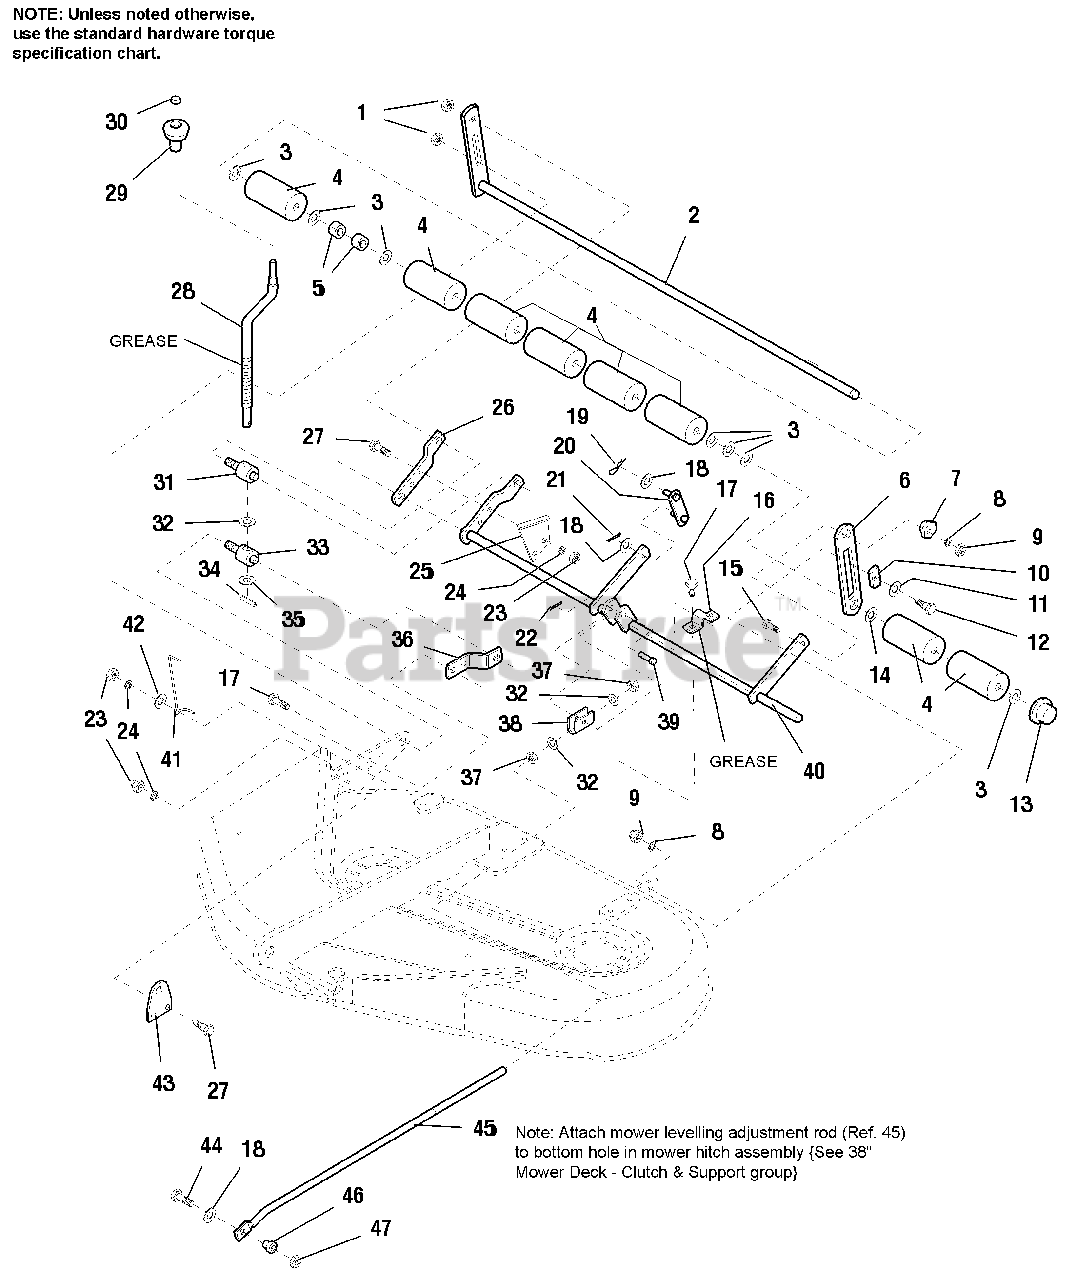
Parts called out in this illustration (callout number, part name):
1	NUT, Hex Flange Lock, 1/2-13
2	SHAFT ASSEMBLY, Roller (Includes Ref. No. 13)
3	WASHER, 5/8
5	SPACER, .66 ID
6	BAR, Roller
7	NUT, Hex Adjusting, .99 DIA .687
8	LOCKWASHER, 3/8
9	NUT, Hex, 3/8-16
11	WASHER, Plain, 1/2
12	BOLT, Shoulder, 3/8-16 X 1.34
13	NUT, Push
14	WASHER, 5/8
15	CARRIAGE BOLT, 3/8-16 x 1-1/2
16	STRAP, Mower Arm ASSEMBLY
17	CAPSCREW, Taptite, 5/16-18 x 3/4
18	WASHER, Plain, 13/32
19	CLIP, Pin, Safety
20	LINK ASSEMBLY, Lift
22	PIN, Hair Clip
23	NUT, Hex, 5/16-18 Whiz Lock
25	BRACKET, Cutting Height
26	ARM, Rear, Mower, RH
27	CAPSCREW, Hex Head, 5/16-18 x 1-1/4
28	CRANK, Cutting Height
30	PAL NUT
31	TRUNNION, Threaded
32	WASHER, 5/8
34	PIN, Roll, 1
35	WASHER, Detent
36	STRAP, Trunnion Retainer
37	NUT, Hex Jam, 1/2-13
39	PIN, Clevis
40	ARM ASSEMBLY, Mower
41	INDICATOR, Cutting Height
42	WASHER, Flat, 5/16
43	PLATE, Support
44	CAPSCREW, Hex Head, 3/8-16 x 1-3/4
45	ROD, Adjustment
47	NUT, Hex Flange, 3/8-16
